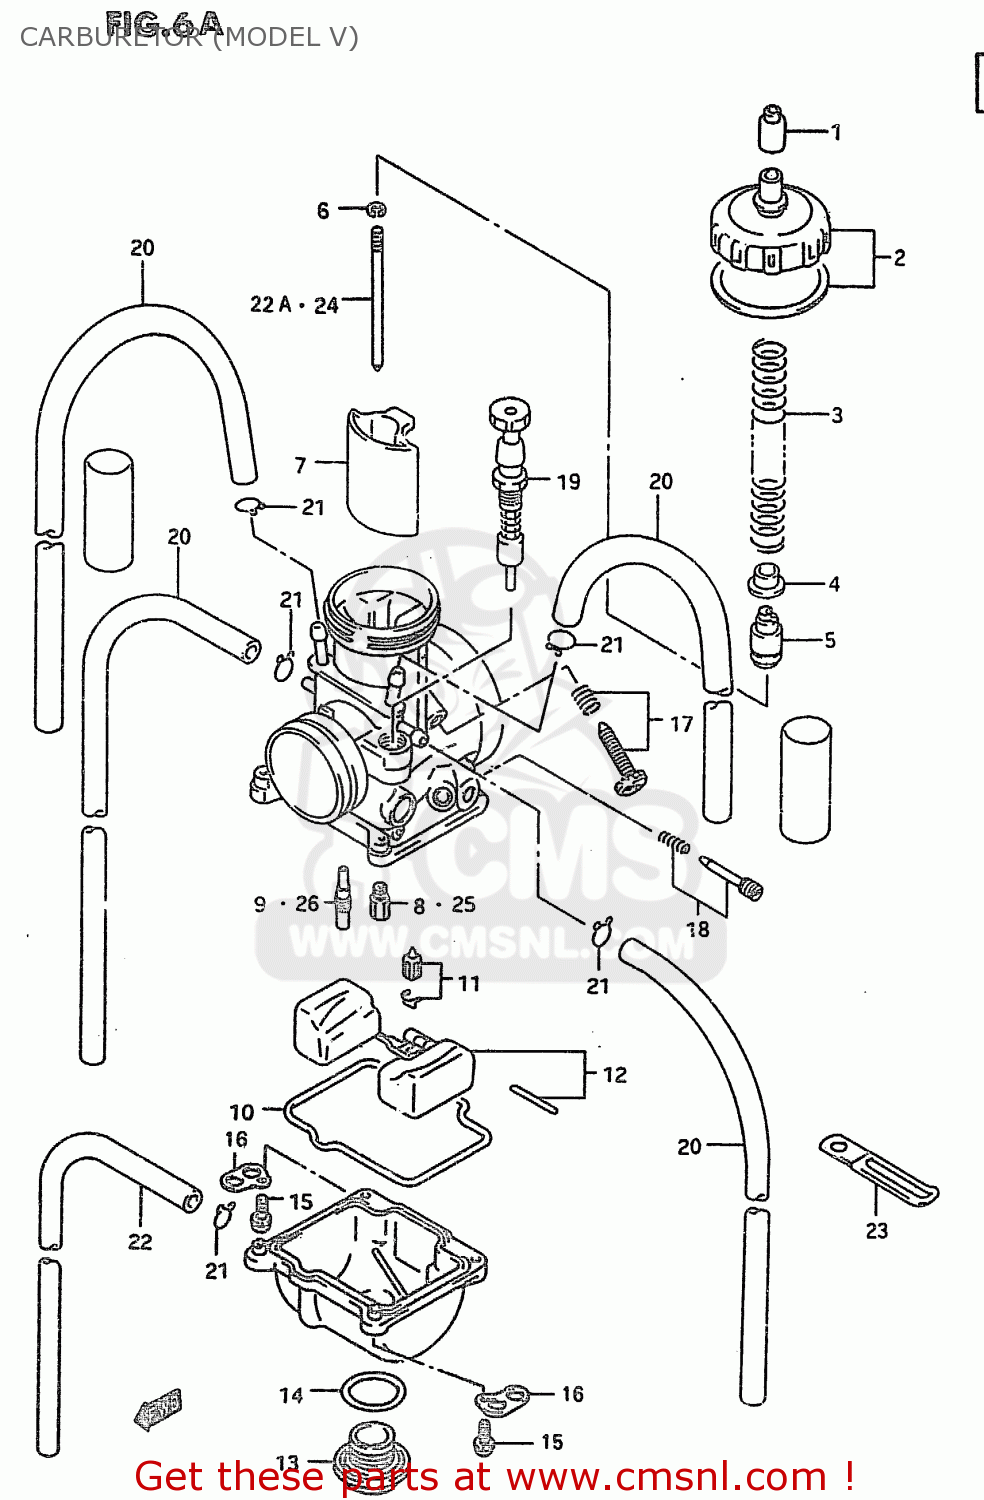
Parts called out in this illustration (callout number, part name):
1	CAP,CARBURETOR
2	CAP SET,TOP
3	SPRING,THROTTLE VALVE
4	COLLAR,THROTTLE VALVE
5	HOLDER,CABLE
6	CLIP,NEEDLE
7	VALVE,THROTTLE
8	JET,MAIN(175)
9	JET,SLOW(48)
10	GASKET,FLOAT CHAMBER
11	VALVE SET,FLOAT
12	FLOAT SET
13	BOLT,DRAIN
14	O RING
15	SCREW
16	PLATE
17	SCREW SET,STOP
18	SCREW SET,AIR
19	STARTER VALVE
20	HOSE(4X7X620)
21	CLIP
22	HOSE(3.5X6.5X600)
22A	NEEDLE(N1ED)
23	CLAMP(L:45)
24	NEEDLE(N1EB)
25	JET,MAIN(160)
26	JET,SLOW(35)
